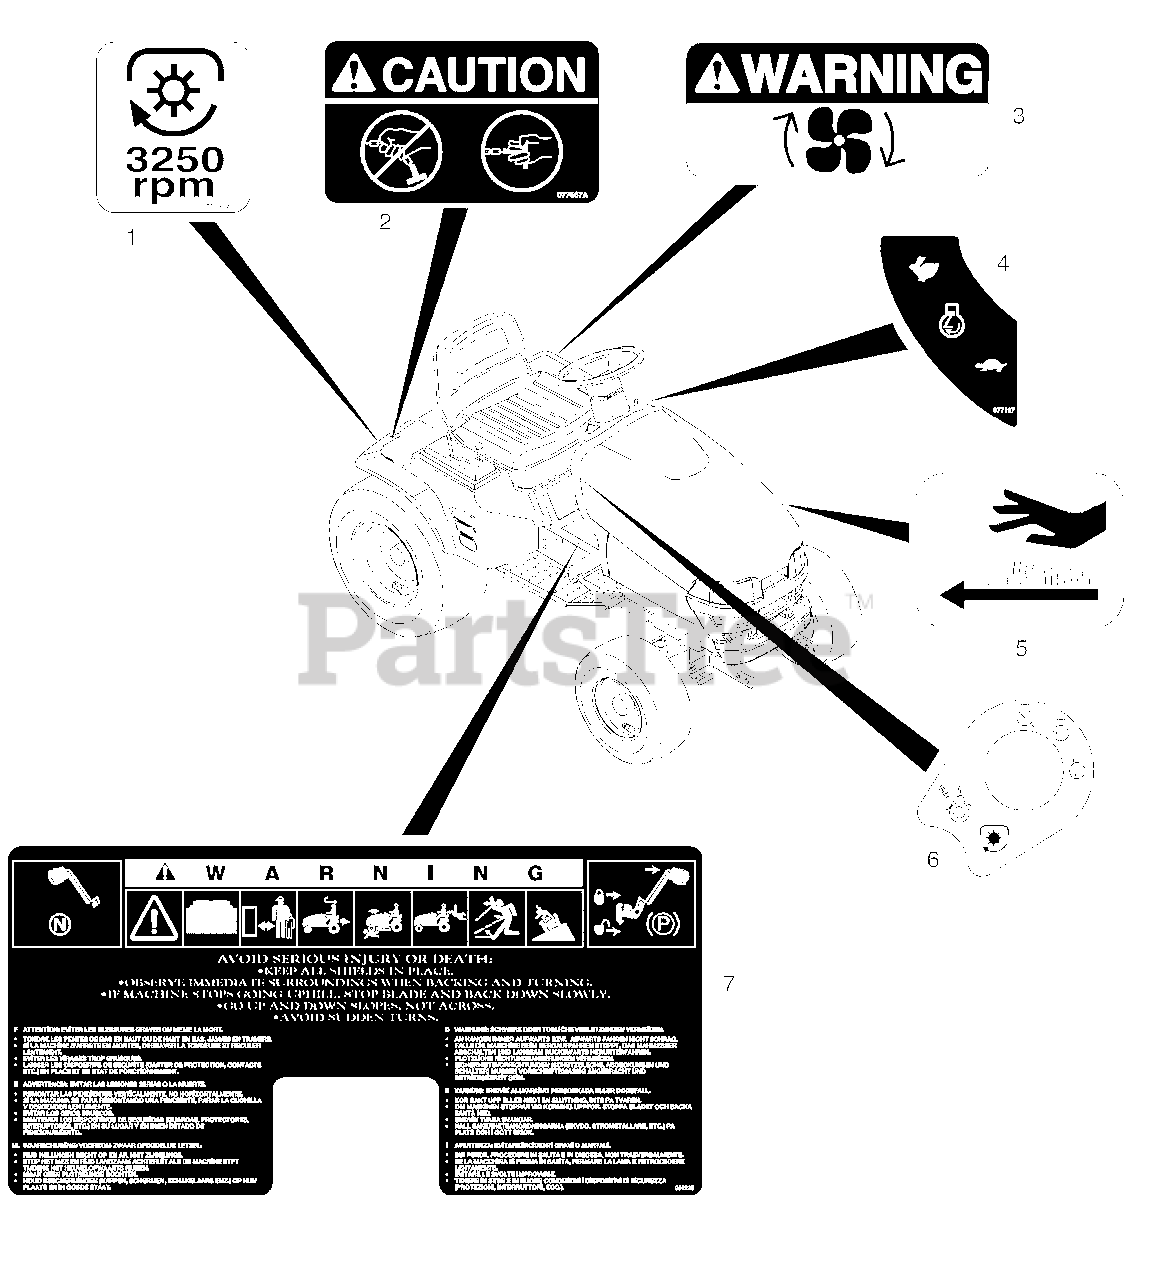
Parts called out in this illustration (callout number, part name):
1	DECAL - PTO SPEED
2	DECAL - CAUTION
3	DECAL - WARNING, FAN
4	DECAL- THROTTLE W/O CHOKE
5	DECAL- HOT SURFACE SYMB.
6	DECAL - IGNITION/PTO
7	DECAL, WARNING INSTRUCTION
